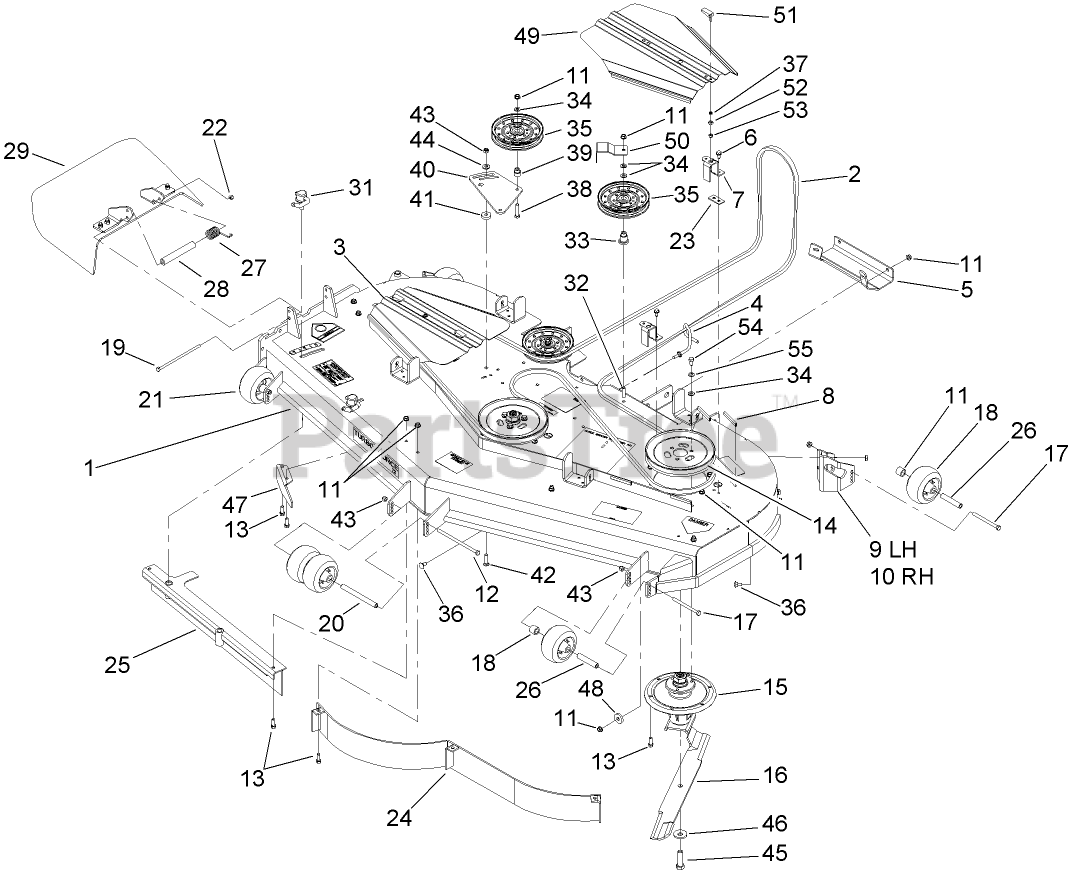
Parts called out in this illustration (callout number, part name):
1	Deck Decal ASM
3	COVER-BELT, RH
4	GUIDE-BELT
5	Plate-Skid
6	SCREW-HWHTF
7	BRACKET-COVER
8	STRIP-SEAL
9	MOUNT-WHEEL, LH
10	MOUNT-WHEEL, RH
11	NUT-HHF, WHIZ
12	SCREW-HH
13	SCREW-HWH
14	Pulley
15	SPINDLE ASM
16	BLADE-HI FLOW, 24.5 INCH
17	SCREW-HH
18	TUBE-SPACER
19	SCREW-HH
20	SPACER-WHEEL
21	ROLLER-SCALP, ANTI
22	NUT-LOCK, NI
23	SPACER-COVER, BELT
26	TUBE-SPANNER
27	SPRING-TORSION
28	SPACER
29	RUBBER DEFLECTOR ASM
31	LEVER ASM
32	SCREW-HH
33	MOUNT-PULLEY
34	WASHER-FLAT
35	Idler-Flat
36	SCREW-CARR
37	WASHER
38	SCREW-HH
39	BUSHING-IDLER
40	Plate-Idler
41	Spacer
42	SCREW-CARR
43	NUT-LOCK, NI
44	WASHER-BELLEVILLE
45	SCREW-BLADE
46	Washer-Blade Bolt, Heavy
47	BAFFLE-DISCHARGE
48	WASHER
49	COVER-BELT, LH
50	GUIDE-BELT
51	HANDLE-LATCH, SWELL
52	BUSHING-LATCH, SWELL
53	NUT-LOCK, HH
54	SCREW-HH
55	WASHER-BELLEVILLE
